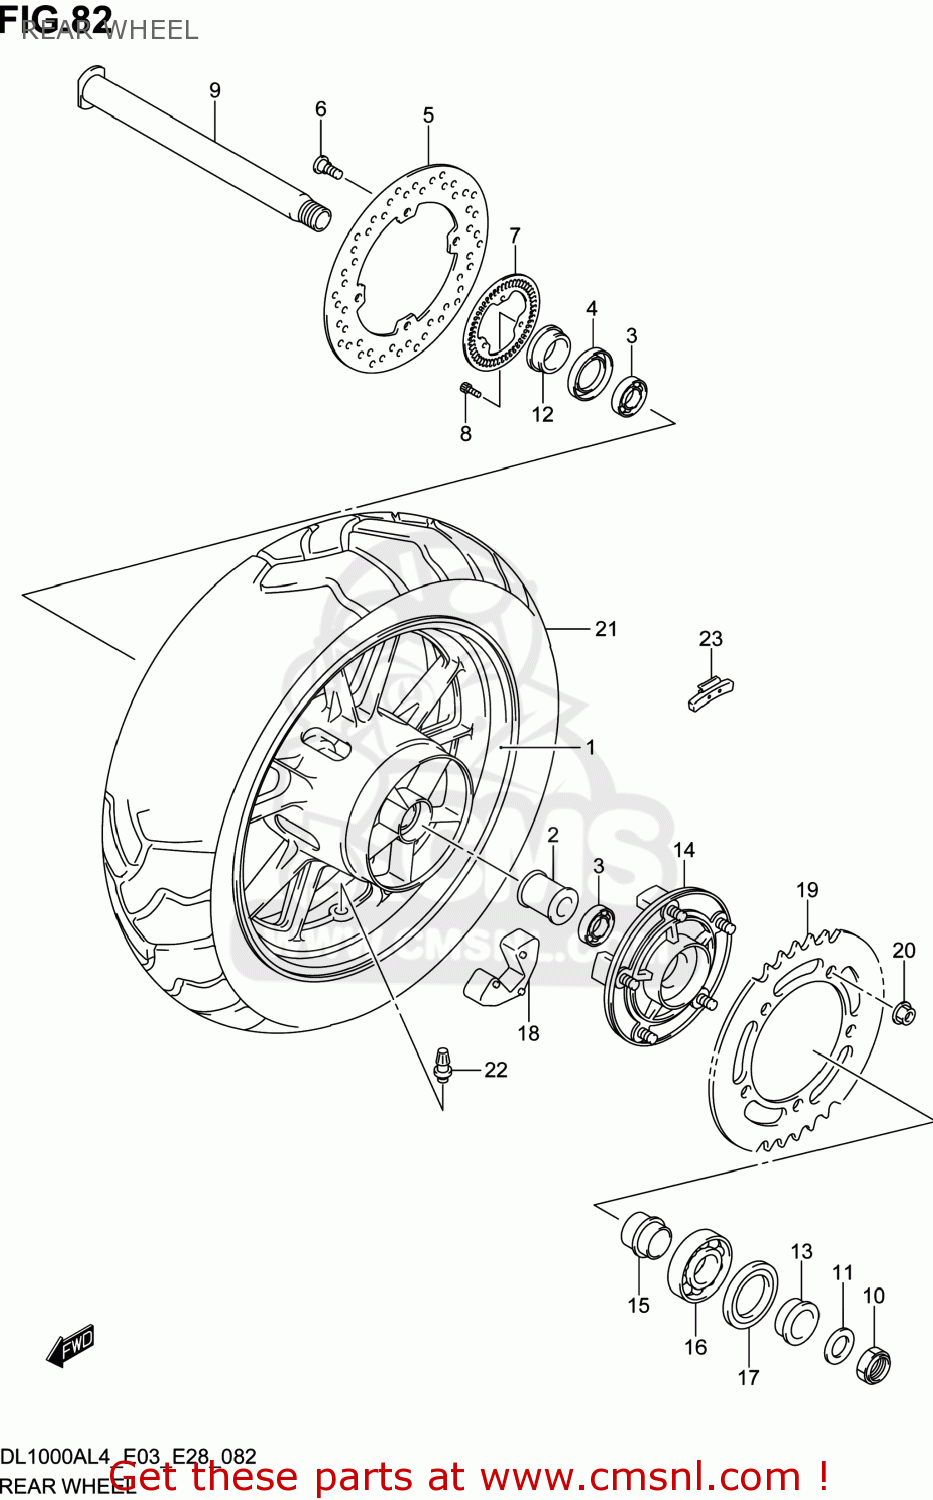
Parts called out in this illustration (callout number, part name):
1	WHEEL,RR(17M/CXMT4.00)
2	SPACER,RR HUB BEARING
3	BEARING(28X52X12)
4	SEAL,OIL(37X52X8)
5	DISC,RR BRAKE
6	BOLT(8X21)
7	RING,SPEED SENSOR RR(50T)
8	BOLT
9	AXLE,RR
10	NUT
11	WASHER(25.2X42X3.2)
12	SPACER,RR AXLE,R
13	SPACER,RR AXLE,L
14	DRUM,RR SPROCKET
15	RETAINER,RR SPROCKET DRUM
16	BEARING(32X65X17)
17	SEAL,OIL(39X65X7)
18	ABSORBER,RR HUB SHOCK
19	SPROCKET,RR(NT:41-525)
20	NUT
21	TIRE,REAR
22	VALVE ASSY,WHEEL RIM(TR412)
23	BALANCER,WHEEL(10G)
